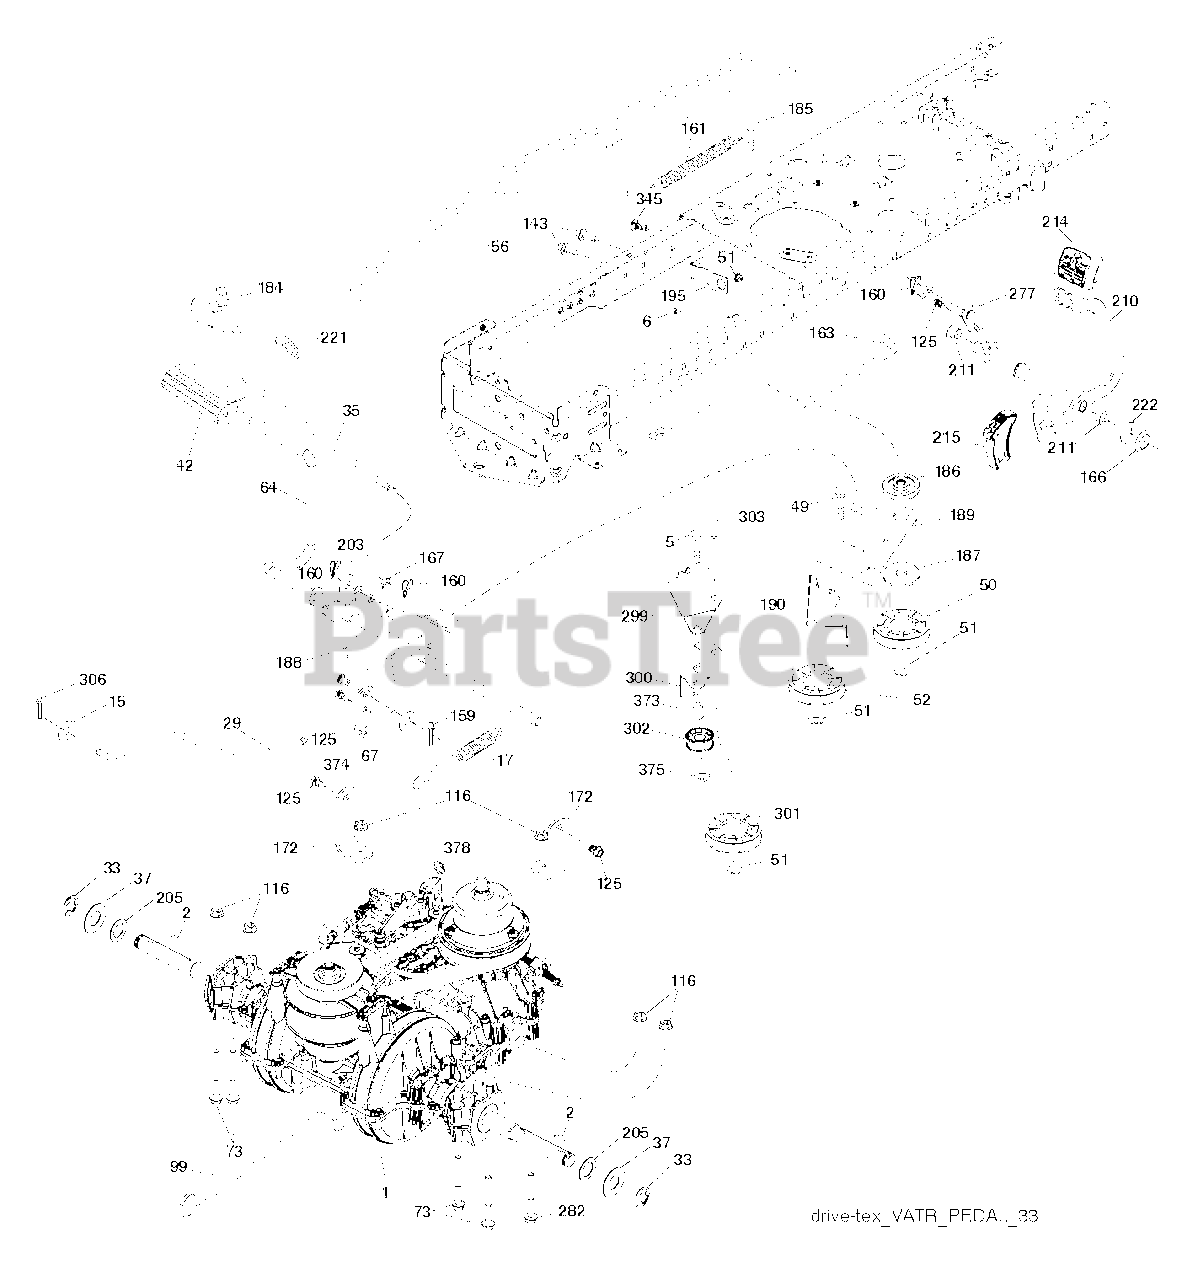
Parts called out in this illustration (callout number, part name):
2	SQUARE KEY
6	BUSHING.SNAP.NYL.BLK.
15	WASHER
17	SPRING BRAKE VARIATOR
29	BRAKE.VARIATOR.SD3
35	ROD .BRAKE. PARKING. GT. HUSQ.
37	WASHER.HARDENED
42	PEDAL COVER T
50	IDLER.FLAT.910.OFFSET
51	NUT LOCK FLG 3/8-16 UNC
52	IDLER.V-GROOVE.910.OFFSET
56	BELT.DRIVE.MOWER.TEX.42"
64	SUBASM.SHAFT.PEDAL.BRAKE
67	WASHER
73	BOLT HEX 5/16-18 GR 5
99	ROD.BYPASS.VARIATOR.GEN2
116	NUT LOCK HEX FLANGE 5/16-18
125	SCREW
143	SCREW LT
159	COTTER PIN
160	RETAINER CLIP
161	SPRING, RETURN LT
163	ROD.CONTROL.PEDAL.VARIATOR
166	NUT.PUSH.625
167	LATCH.BRAKE.SPRING
172	STRAP.TORQUE.VARIATOR
184	HANDLE.PARKING.BRAKE.H (BLK)
186	SPACER.RETAINER
187	WASHER 12/32X2X10GA
188	RP LINK.CLUTCH.GROUND.DRIVE
189	BELLCRANK.GROUND.DRIVE.TEX.
190	KEEPER.BELLCRANK.DRIVE
195	BRACKET.BRAKE.BRAKE.VAR.SD
203	WASHER
210	WELDMENT.PEDAL.VARIATOR
211	BUSHING.SHAFT.BRAKE.HAND
214	PEDAL.FORWARD.PAD.TEX
215	CAP.PEDAL.REVERSE.VARIATOR
221	RETAINER.SPRING.CLIP.H
222	WASHER 21/32 X 1-1/4 X 10 GA.
277	SUBASM.LINK.ROCKER.PEDAL
282	BOLT HEX FLGHD 5/16-18X3 GR. 5
299	BRACKET.MOUNT.IDLERS
300	KEEPER.IDLERS.REAR.VARIATOR
301	PULLEY.IDLER.V-GROOVE
303	BOLT CARRIAGE
306	PIN COTTER
373	SPACER.IDLER
374	ARM.CONTROL.BRAKE
378	NUT.PUSH.8MM
